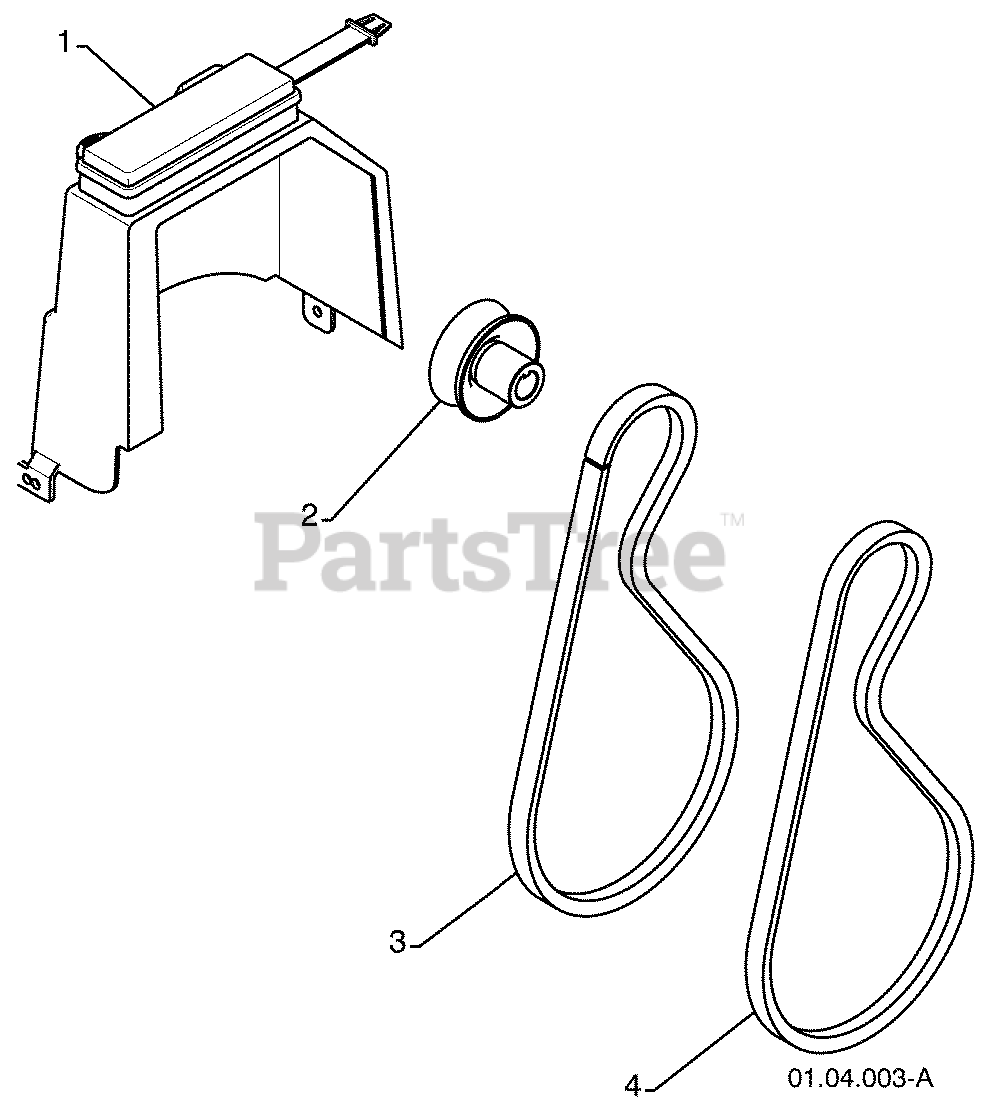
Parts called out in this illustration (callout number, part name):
1	COVER.ASM.BELT/STORAGE
2	PULLEY, ENGINE IMPELLER DRIVE
3	V-BELT TRACTION 34.25
4	BELT.V.IMPELLER
